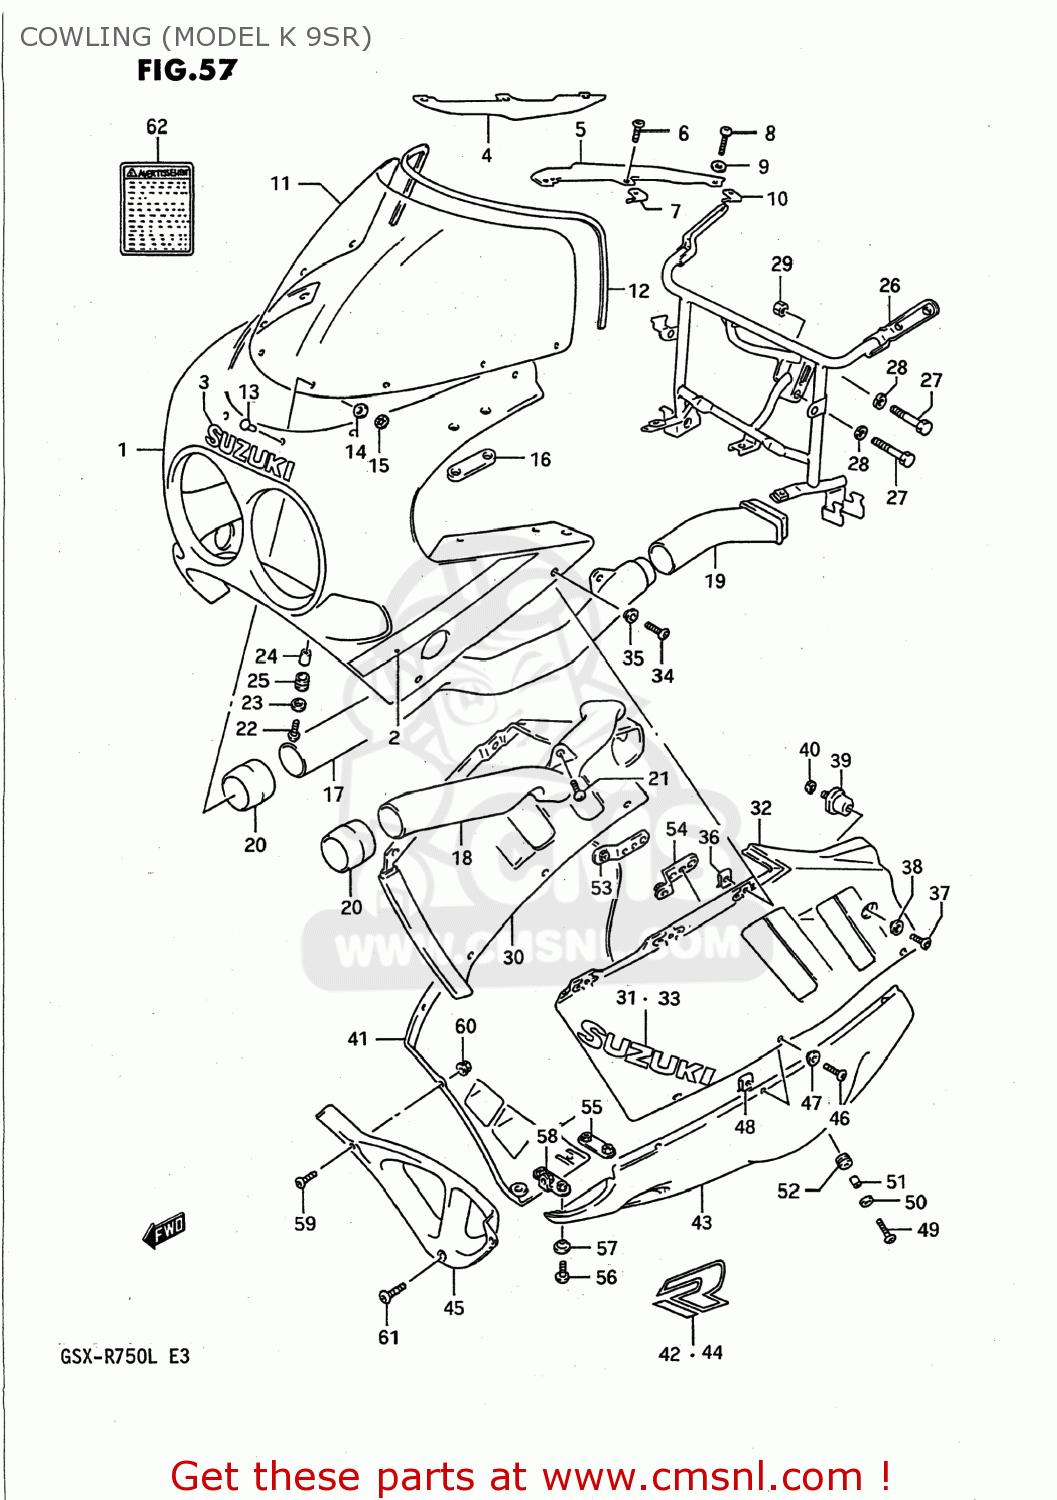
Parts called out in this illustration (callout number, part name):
1	BODY ASSEMBLY,COWLING
2	TAPE SET,COWLING,UPPER
3	EMBLEM,COWLING,UPPER (W)
4	PANEL,COWLING UPPER,RIGHT
5	COVER,COWLING,LEFT
6	SCREW(5X10)
7	NUT
8	SCREW(5X14)
9	WASHER(5.2X11X1)
10	NUT
11	WINDSCREEN
12	MOLDING,WINDSCREEN
13	PIN,WINDSCREEN
14	CUSHION
15	NUT
16	CUSHION,RR VIEW MIRRORR
17	PIPE,AIR INTAKE,FRONT
18	PIPE,AIR INTAKE,FRONT
19	PIPE,AIR INTAKE RR,R
20	JOINT,AIR INTAKE
21	SCREW
22	SCREW(6X20)
23	WASHER(6.5X18X1)
24	SPACER
25	CUSHION
26	BRACE,COWLING
27	BOLT
28	WASHER,LOCK,8.
29	NUT ,8MM
30	COVER,COWLING SIDE,RIGHT
31	EMBLEM
32	COVER,COWLING SIDE,LEFT
33	EMBLEM
34	SCREW(5X18)
35	WASHER(5.2X14X1.5)
36	NUT,HEADLAMP HOUSING,UPPER
37	SCREW(6X12)
38	WASHER(6.3X16X1.5)
39	CUSHION,COWLING
40	WASHER,LOCK
41	COWLING,UNDER,RIGHT
42	EMBLEM,COWLING UNDER
43	COWLING,UNDER,LEFT
44	EMBLEM,COWLING UNDER
45	COWLING,UNDER,CENTER
46	SCREW(5X18)
47	WASHER(5.2X14X1.5)
48	NUT,HEADLAMP HOUSING,UPPER
49	SCREW(6X20)
50	WASHER(6.5X18X1)
51	SPACER
52	CUSHION
53	BRACKET
54	BRACE,COWLING UNDER,LH
55	BRACE,COWLING LWR COVER RR
56	SCREW(6X16)
57	WASHER(6.3X16X1.5)
58	BRACE,COWLING LWR COVER
59	SCREW(5X14)
60	NUT
61	SCREW(6X16)
62	LABEL (WARNING SCREEN)
